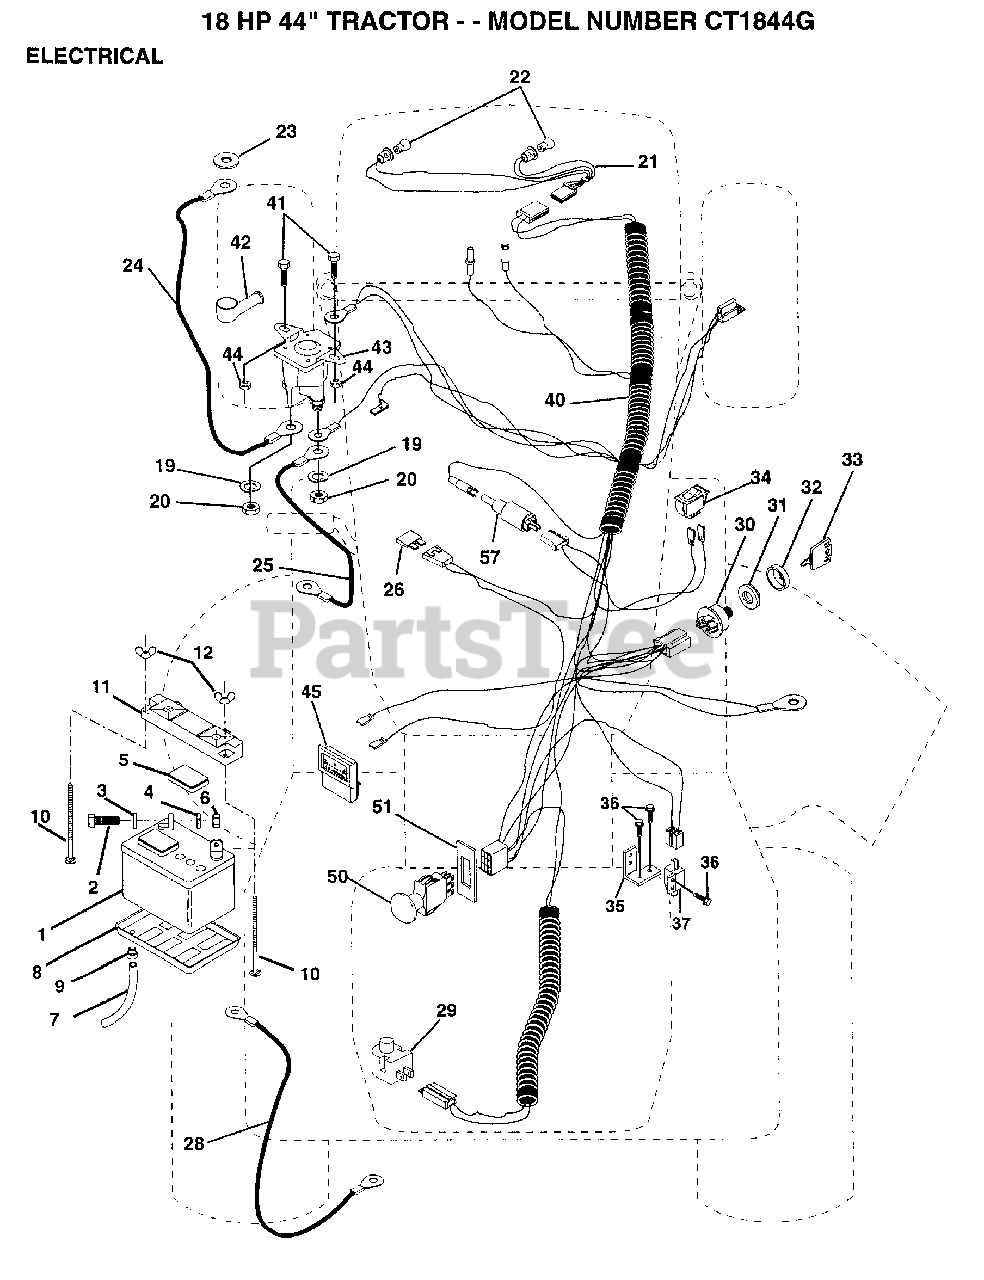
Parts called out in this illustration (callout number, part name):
2	BOLT LT
3	WASHER
4	LOCKWASHER
5	"CAP,BATTERY "
7	"DRAIN TU T, BATT"
8	"TRAY T, BATTERY"
9	HOSE CLAMP T
10	BOLT
20	NUT
21	"HARNESS,LIGHT SOC"
22	HEADLAMP BULB
23	LOCKWASHER
24	"CABLE T, BATTERY"
25	CABLE-BATTERY T
26	FUSE HYT
28	CABLE T
29	SWITCH SEAT
32	COVER KEY SWITCH
33	KEY MLD GEN DELTA
34	SWITCH LT
35	BRACKET SWITCH IN
36	SCREW
37	SWITCH-INTER. GT
40	HARNESS.IGN.PTO.
41	BOLT HXHD FIN
44	NUT HXKEP 1/4X20
51	RING RETAIN PTO
57	DIODE ASM.
